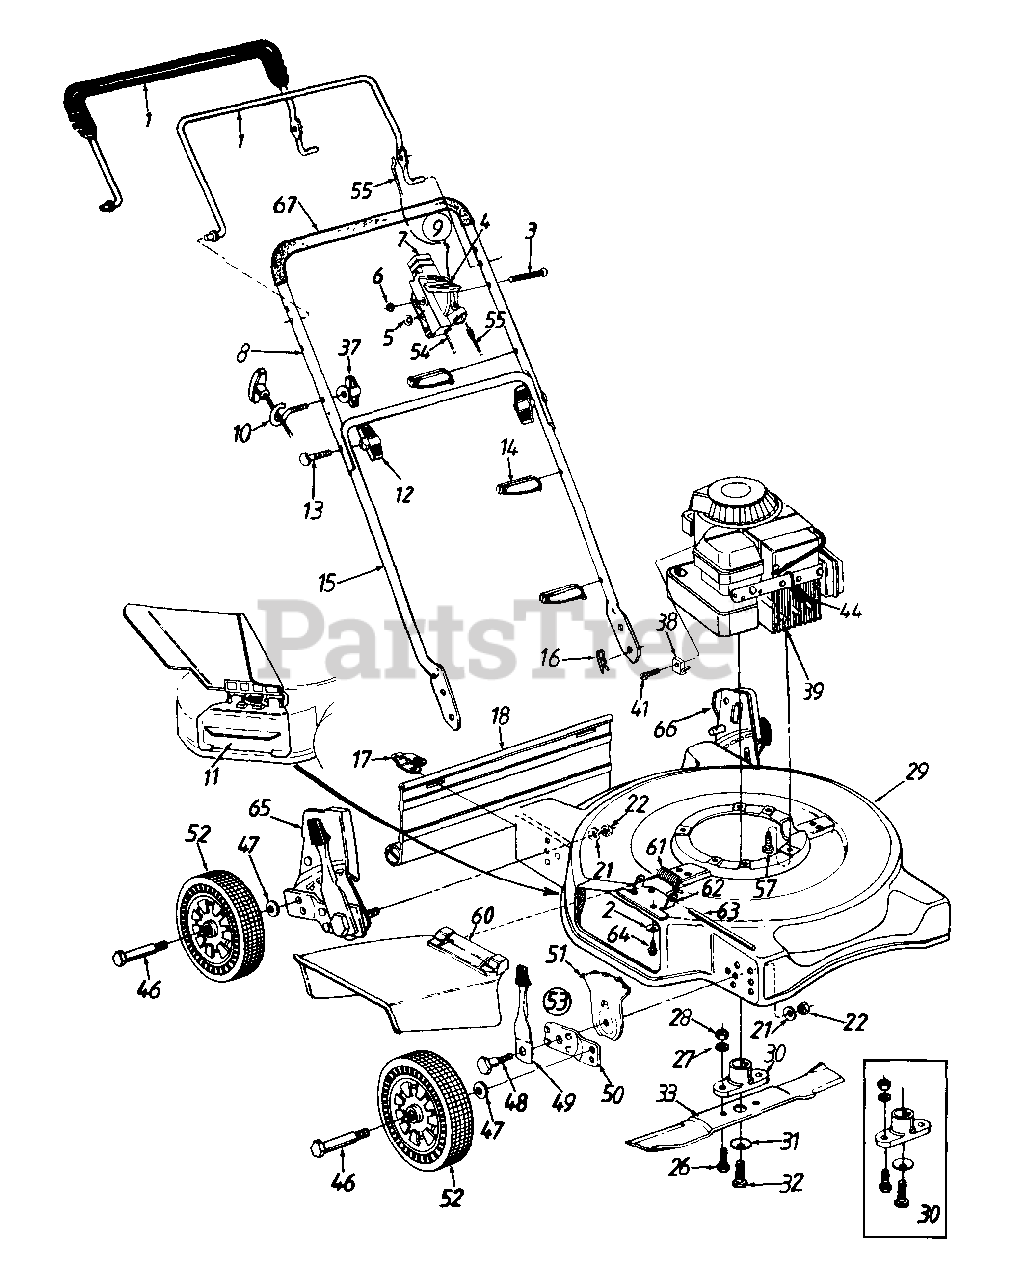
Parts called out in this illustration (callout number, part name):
2	Bell-Wash. 1/4" I.D.
3	Oval C-Sunk Mach. Scr.
4	Throttle Lever
5	Spr. Wash. .66" I.D.
6	Hex L-Nut 1/4-20 Thd.
7	Throttle Body
10	Rope Guide
11	Mulching Plug
12	Hand Knob
13	Curved Hd. Bolt 5/16-18 x 2" Lg.
14	Cable Tie
16	Hairpin Cotter
17	Hinge Clip
18	Rear Flap (20")
22	Hex Nut 3/8-16 Thd.
26	Hex Bolt 3/8-24 x 1" Lg.
27	L-Wash. 3/8" I.D.
28	Hex Nut 3/8-24 Thd.
31	Bell-Wash. .39" I.D.
32	Hex Bolt 3/8-24 x 1.5" Lg.
33	20" Blade
37	Wing Nut 1/4-20 Thd.
38	Cable Clamp
39	Engine
41	Hex Wash. Hd. Tap Scr. #10-32 x .62" Lg.
44	Spark Plug Boot
46	Axle Bolt
47	Bell-Wash. .400" I.D. x .88"
48	Shld. Bolt .50" Dia. x .357"
49	Spring Lever Ass'y. w/Knob
51	Height AdJ. Plate
52	Wheel Ass'y. Comp.
53	Height Adj. Ass'y. Comp. - R.F.
54	Throttle Cable - 51"
55	Control Cable - 39"
57	Hex L-Wash. Hd. Scr. 3/8-16 x 1.0" Lg.
60	Chute Deflector Ass'y.
61	Torsion Spring
62	Adapter Plate
63	Hinge Pin
64	Hex Self-Tap Scr. 1/4-20 x .5"
67	Foam Grip
